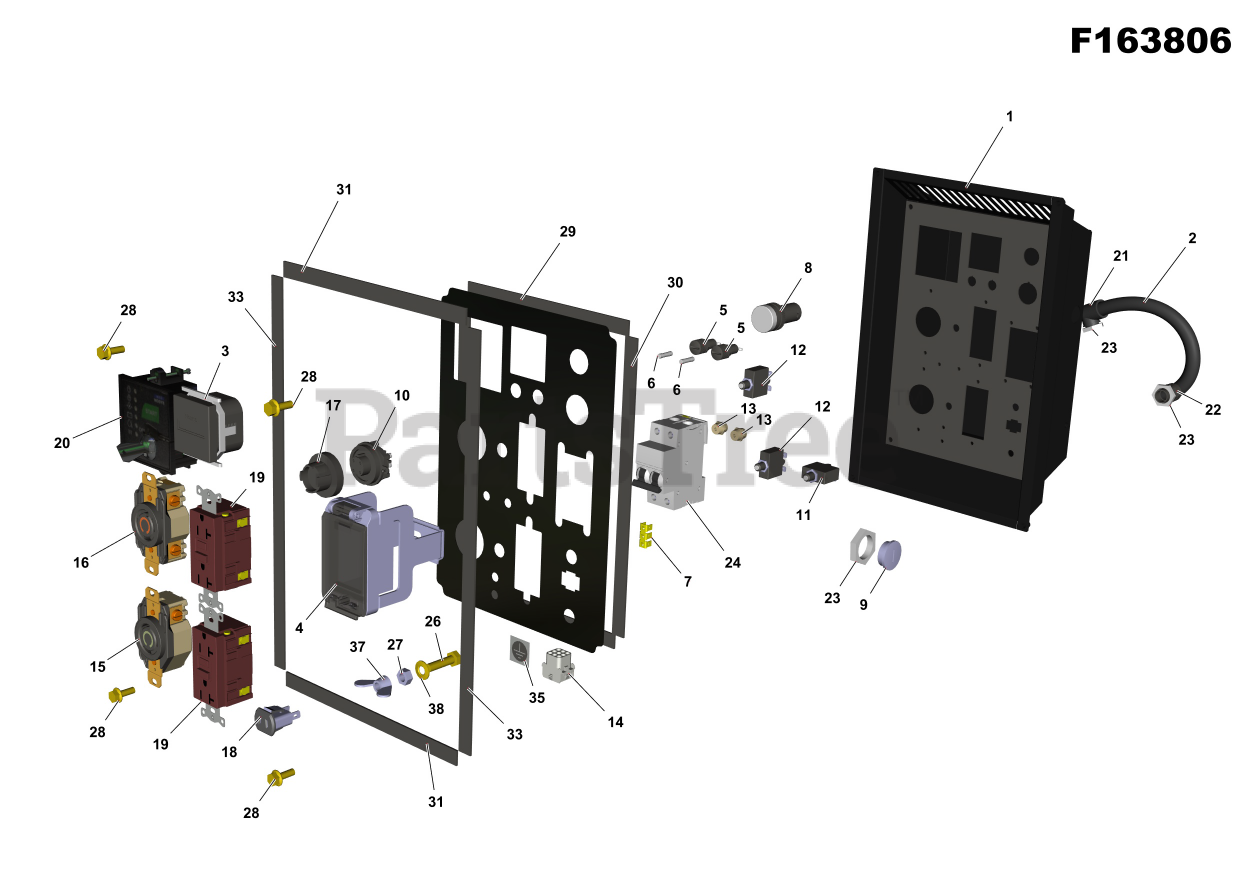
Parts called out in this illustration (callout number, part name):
3	HOUR METER
5	FUSE HOLDER
8	INDICATOR LIGHT W/BLUB
11	CIRCUIT BREAKER
12	CIRCUIT BREAKER
13	INSULATOR
14	CONNECTOR
24	CIRCUIT BREAKER
29	SEAL, LINEAR
30	SEAL, LINEAR
31	SEAL, LINEAR
33	SEAL, LINEAR
